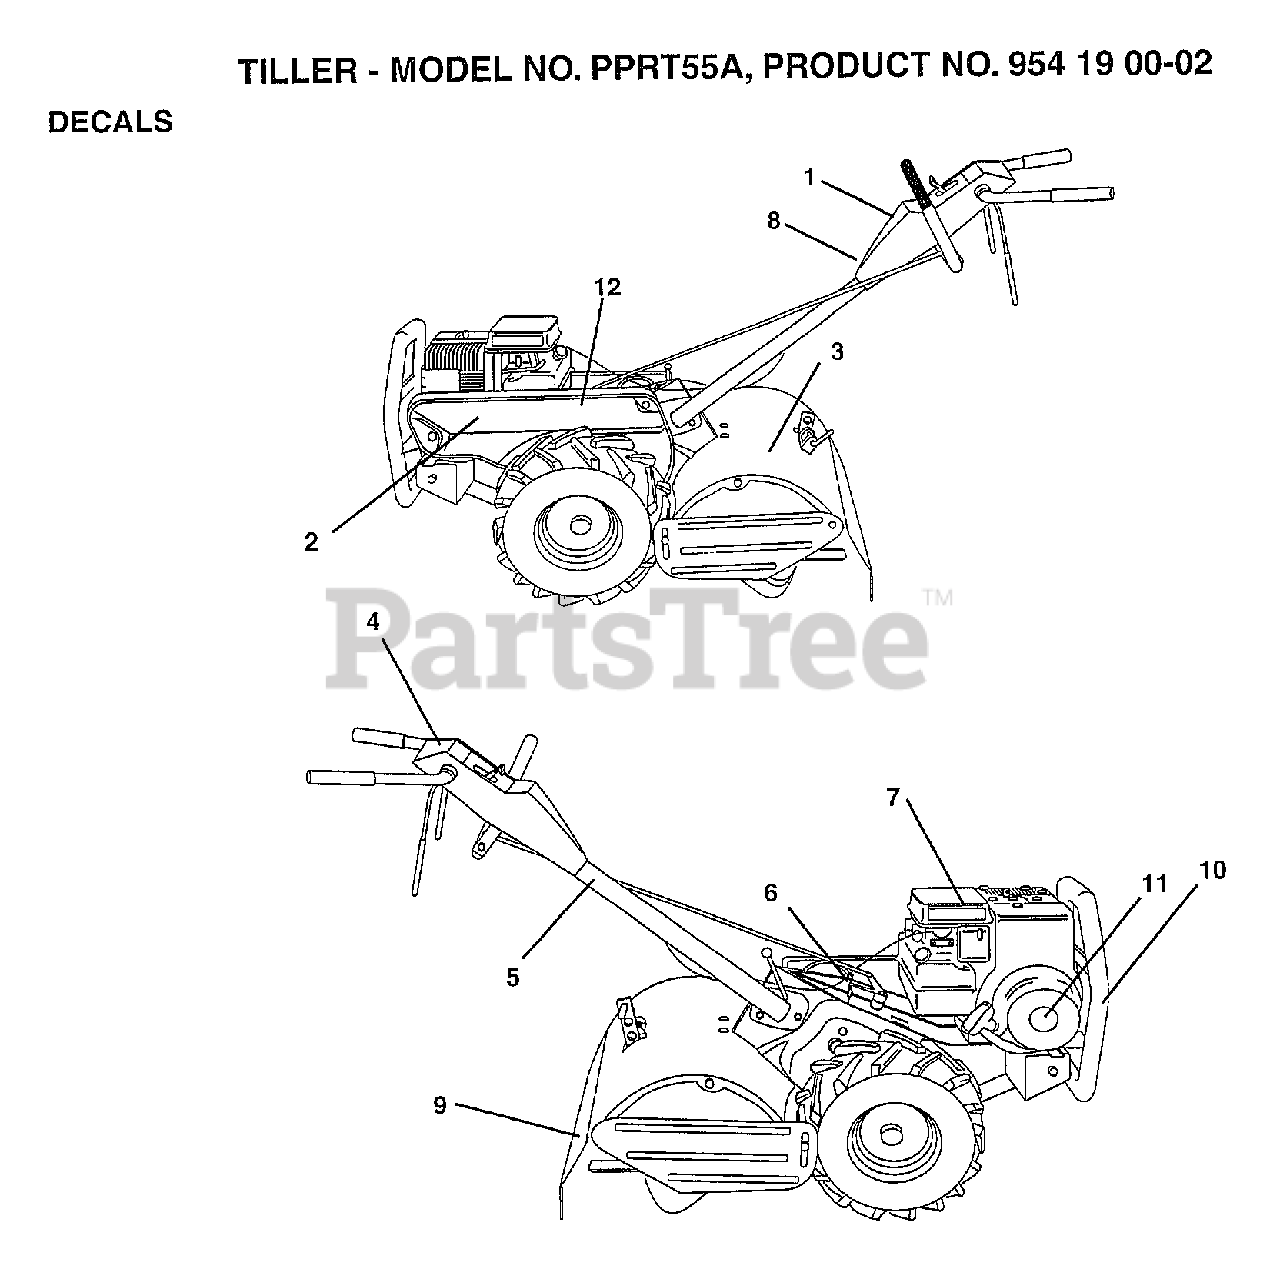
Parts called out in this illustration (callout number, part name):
1	DECAL, LOGO
2	DECAL.FENDER.BELT.GUARD
3	DECAL, LOGO
4	DECAL.INSTRUCTION
5	DECAL HAND PLACEMENT
6	DECAL, SHIFT INDICATOR
8	DECAL, CONTROL PANEL
9	DECAL WARNING ROTATING TINES
10	DECAL, BUMPER/GRILLE
11	DECLA ENGINE
12	RETAINER-SPRING
